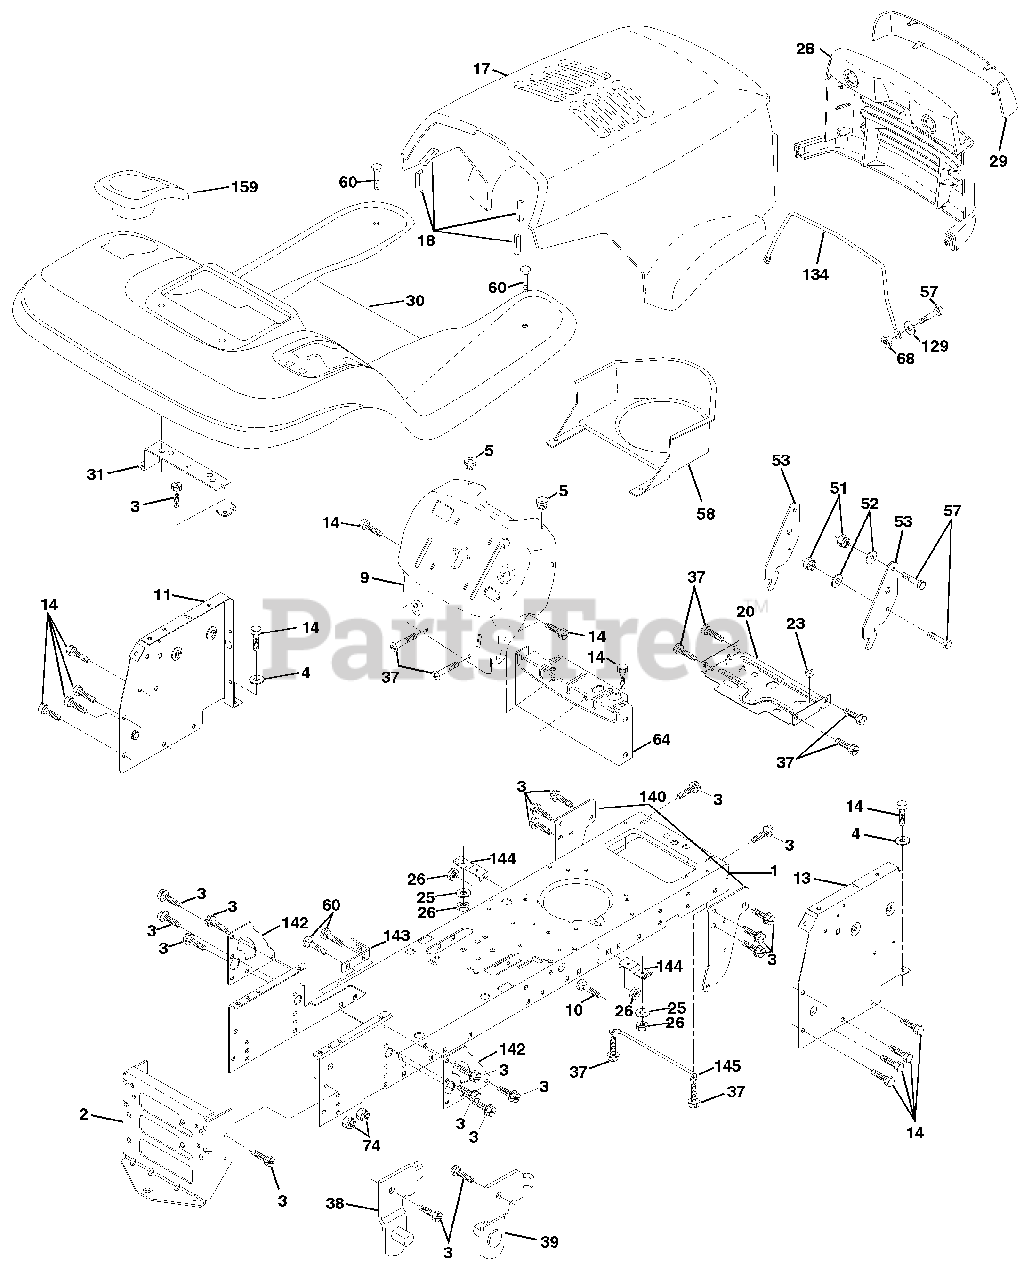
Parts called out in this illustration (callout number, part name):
1	Chassis Weldment
2	Drawbar, Stretch
3	Screw Thdrol 3/8-16x3/4 Ty-tt
4	Washer 13/32 x 3/4 x 16 Ga.
5	Bumper Hood/Dash
9	Dash P/L M, Slkscr Mech Na N/HM
10	Bolt Carriage 3/8-16 x 1
11	Panel Dash Lh
13	Panel Dash Rh
14	Screw Thdrol 3/8-16x1/2 Ty-tt
17	Hood LT/PL Husqvarna
18	Bumper Hood
20	Plate Mtg Battery Fuel Tank Fr
25	Washer 13/32 X 13/16 X 12 Ga
26	Nut Lock Hex W/Ins 3/8-16 Unc
28	Grille LT/PL Husqvarna
29	Lens LT/PL Husqvarna
30	Fender Footrest STLT Pnt
31	Bracket Support Fender
37	Screw Thdrol 6/16-18 x 1/2 TYT
38	Bracket, Asm. Pivot, L.H., Mower Rear
39	Bracket, Asm. Pivot, R.H., Mower Rear
51	Nut Lock Hex W/Ins 1/4-20
52	Washer 9/32 x 7/8 x 16 Ga.
53	Bracket Pnt. Pick off LT/PL Husqvarna
57	Bolt Hex 1/4-20 x 3/4
58	Air Duct Engine P/L
60	Bolt Rdhd Sqnk 3/8-16unc x 3/4
64	Dash Lower STLT
68	Nut Keps Hex 1/4-20 Unc
74	Nut Crownlock 3/8-16 UNC
129	Washer 9/32 x 5/8 x 16 Ga.
134	Rod Support Hood LT/PL Husq.
140	Bracket Suspension Front
142	Plate Reinforcement STLT
143	Bracket Swaybar Chassis
144	Bracket Pnt Footrest STLT
145	Rod Pivot Chassis/Hood
159	Cupholder STLT Grey
